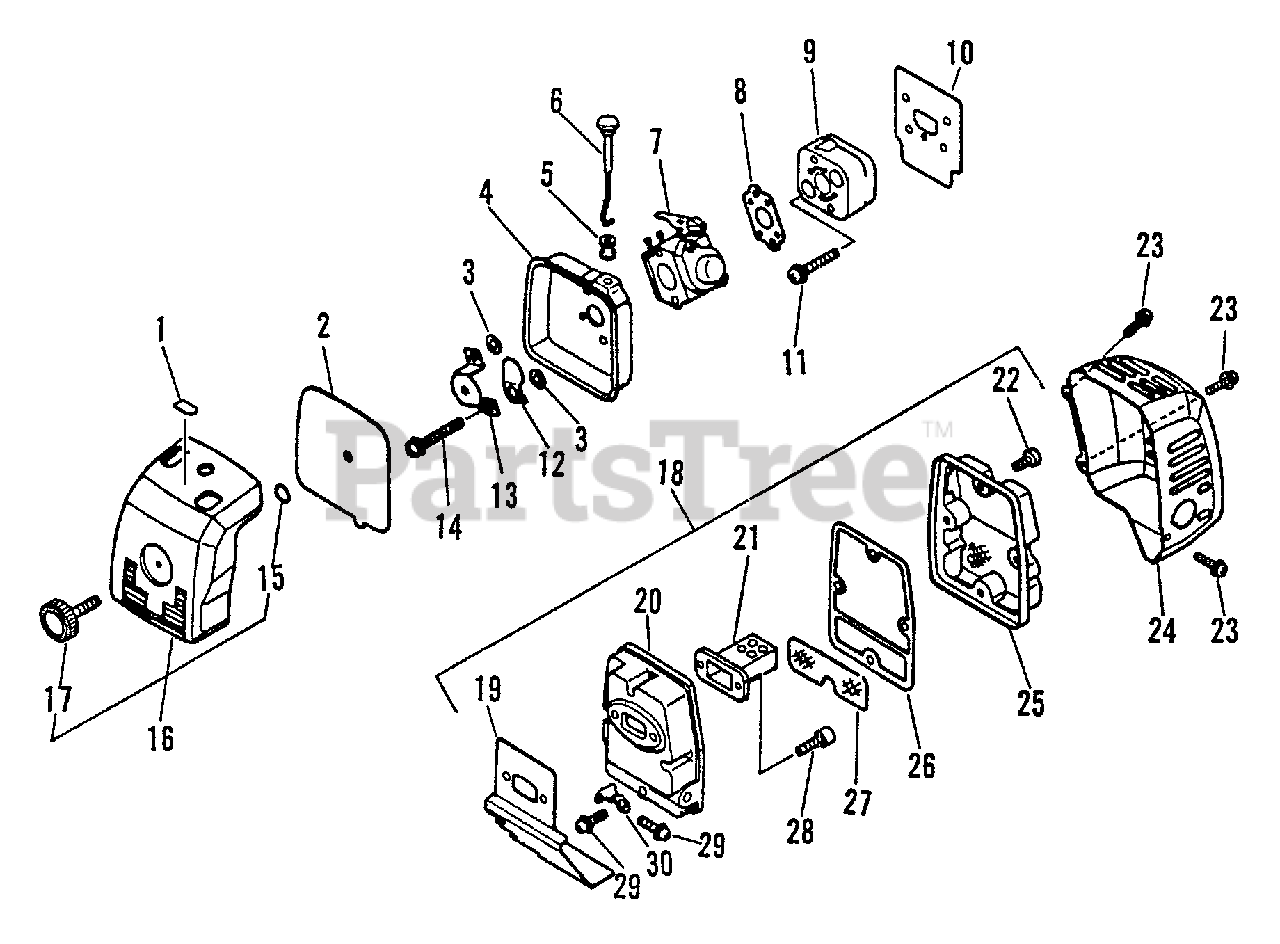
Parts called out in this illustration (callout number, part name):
1	LABEL - CHOKE
2	FILTER, AIR
3	WASHER - 5
4	CASE, AIR FILTER
6	ROD, CHOKE
7	CARBURETOR C1U-K20
8	GASKET, INTAKE
9	INSULATOR, INTAKE
10	GASKET, INTAKE
11	SCREW - 5X25
12	SHUTTER, CHOKE
13	PLATE, PREVENT
14	SCREW - 5X50
15	O-RING - 3
16	AIR FILTER COVER ASSY
17	THUMBSCREW
18	MUFFLER ASSY
19	GASKET, EXHAUST
21	BAFFLE, MUFFLER
22	SCREW - 5X14
23	SCREW - 4X8
24	COVER, MUFFLER
25	LID, MUFFLER
26	GASKET, EXHAUST
27	SCREEN, SPARK ARRESTOR
28	SCREW - 5X18
29	SCREW - 5X10
30	BRACKET, MUFFLER
